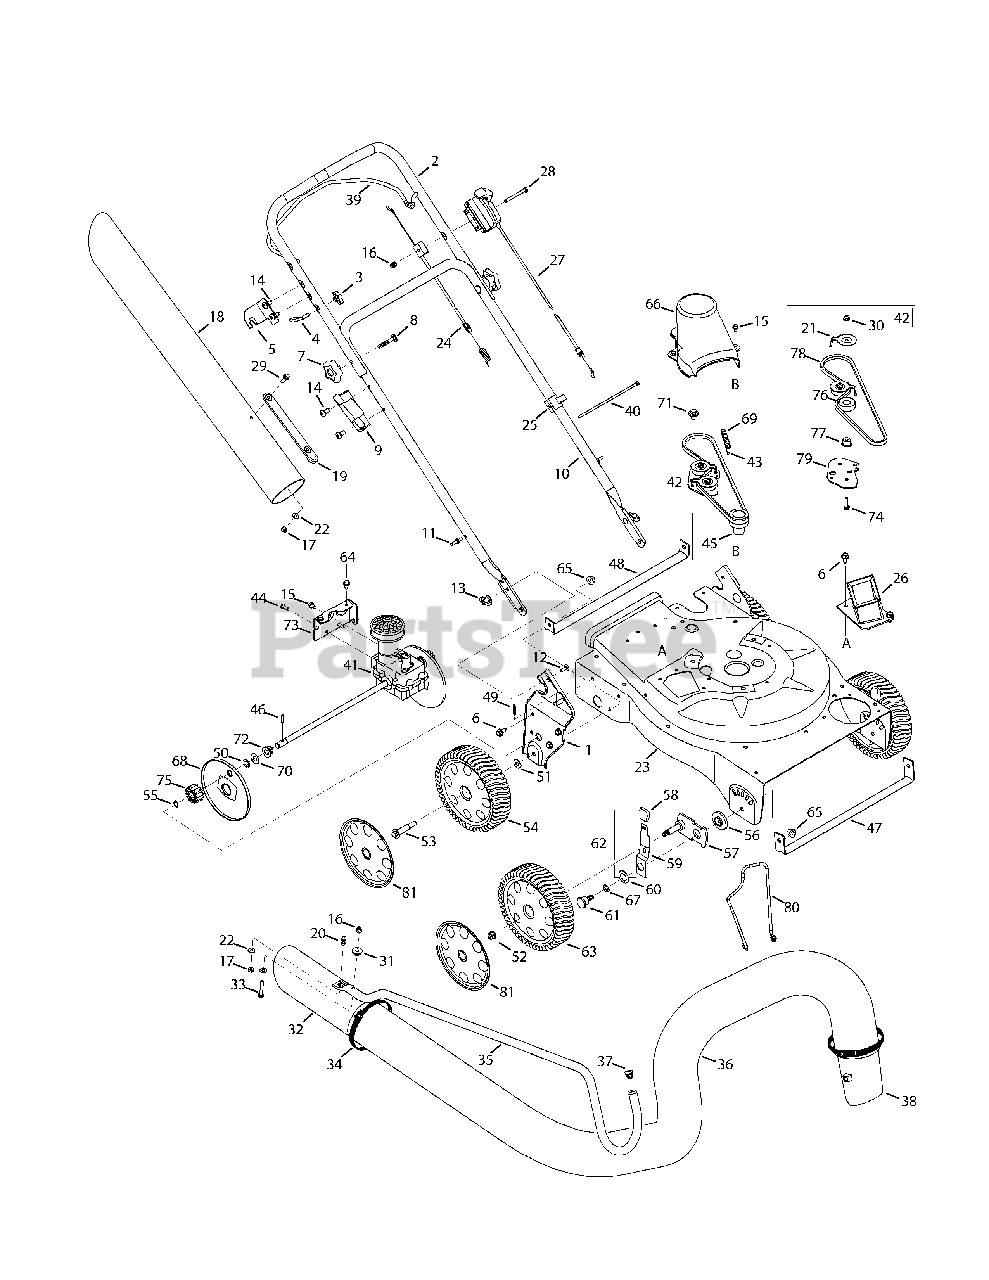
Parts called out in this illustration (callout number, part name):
1	Handle Bracket Ass’y RH
2	Upper Handle
5	Upper Handle Bracket
6	Hex Cap Screw, 5/16-12 x.750
7	Handle Knob, 5/16-18
8	Carriage Bolt
9	Nozzle Handle Clip
12	Carriage Screw, 1/4-20 x.75
13	Wing Nut, 1/4-20
14	TT Screw, 5/16-18 x .750
15	Screw, 1/4-20 x .500
16	Cap Lock Nut, 1/4-20
17	Hex Lock Nut, 1/4-20
18	Hose Extension
19	Chute Strap
21	Belt Keeper
22	Flat Washer.271 ID x.630 OD
23	Upper Flail Housing
24	Drive Control Cable
25	Cable Guide
26	Chipper Chute Assembly
27	Speed Control Cable
28	Hex Screw, 1/4-20 x 2.50
29	Screw, 1/4-20 x .75
30	Flange Lock Nut, 1/4-20
32	Hose Nozzle
33	Hex Cap Screw, 1/4-20 x 2.625
34	Adjustment Clamp
36	Vacuum Hose
37	Handle Plug
38	Hose Adapter
39	Drive Control
40	Cable Tie
41	Transmission Assembly
42	Idler Assembly (Incl. Ref.# 76-79)
43	Shoulder Screw, #12-24 x .30 x .46
44	Screw, #12-16 x .750
45	Impeller Hub
46	Dowel Pin
47	Front Wheel Support Brace
48	Rear Wheel Support Brace
49	Cotter Pin
51	Flat Washer, .406 x .875 x .105
52	Flange Lock Nut, 3/8-16
53	Shoulder Screw, 3/8-16
54	Wheel, 8 x 2
55	Snap Ring
56	Height Adjustment Bearing
57	Pivot Arm Assembly
58	Height Adjustment Knob
59	Spring Lever
60	Bell Washer, .760 ID x.25 OD
61	Shoulder Screw, .750 x.500
62	Height Lever Assembly (Incl. Ref.# 58-59)
63	Wheel 8 x 2
64	Screw, 1/4-20 x .625
65	Flange Lock Nut, 3/8-16
66	Belt Cover
67	Thrust Washer, .375 ID x.70 OD
68	Wheel Cover
69	Extension Spring, .375 x 2.95
70	Flat Wash, .508ID x1.00OD x.020
71	Shoulder Screw, .560 x.165
72	Drive Axle Bushing
73	Transmission Mounting Bracket
74	Screw, 1/4-20 x 1.00
75	Spur Gear - RH
76	Ball Bearing
77	Flange Spacer,.260 x.659 x.517
78	Belt, 3/8 x 32.5
79	Idler Bracket
80	Tube Holder
81	Hubcap, 8"
